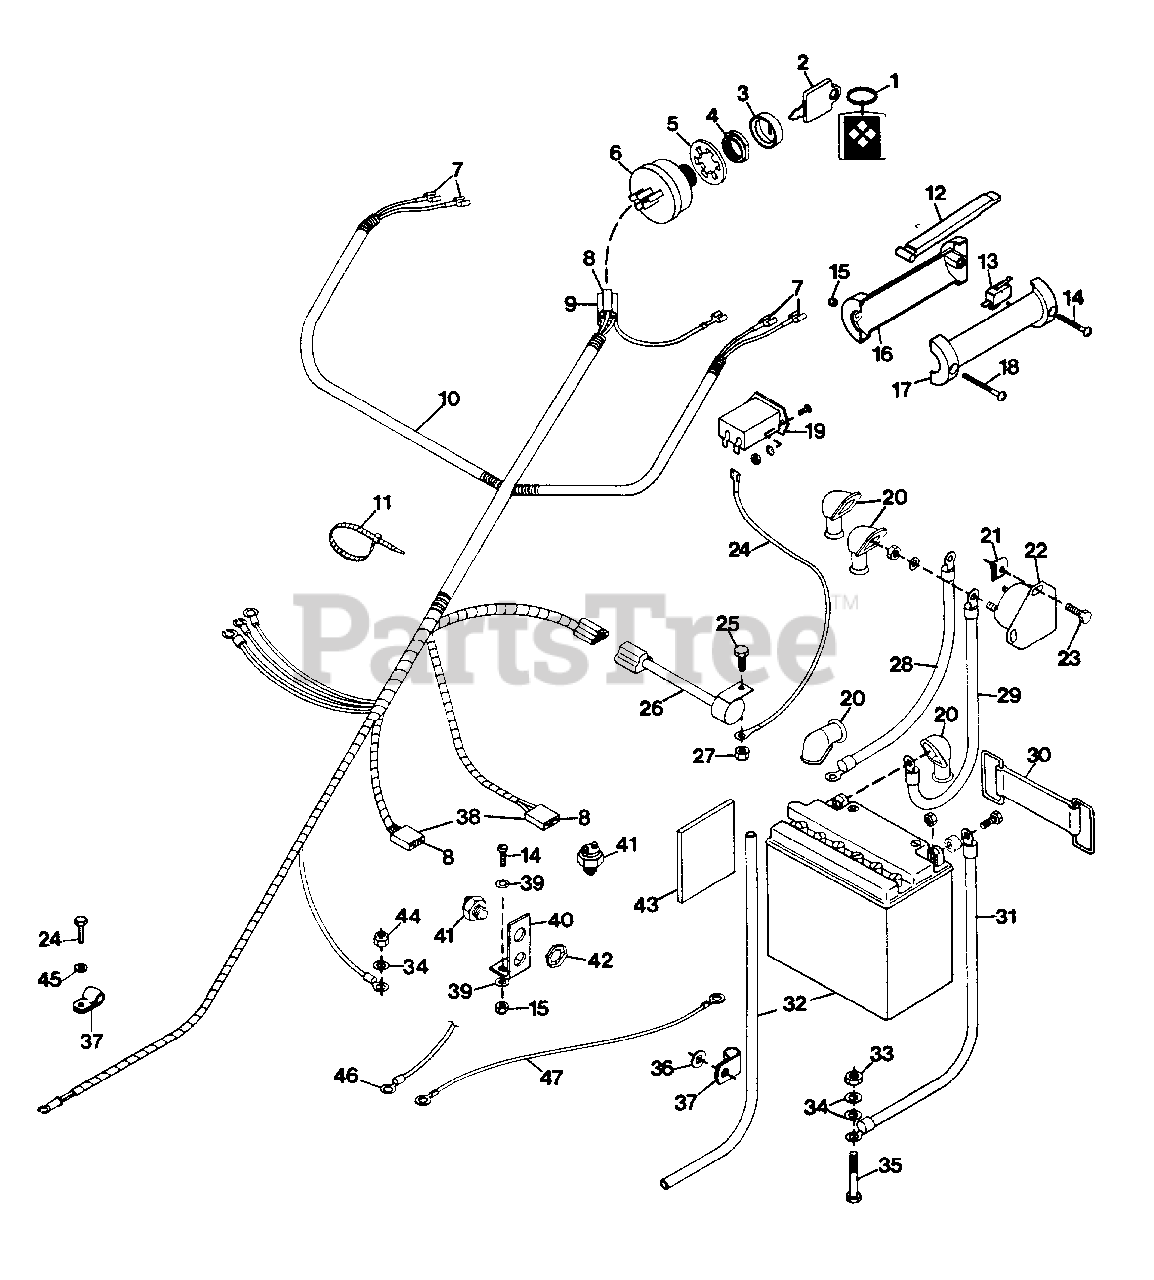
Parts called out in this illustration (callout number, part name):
1	CHAIN, KEY
2	KEY, IGNITION SWITCH
3	BOOT, FOR 9/16 SWITCH
4	NUT, 9/16-24 FOR SWITCH
5	WASHER, LOCK
6	SWITCH, IGNITION
7	TERMINAL, FEMALE
8	TERMINAL
9	CONNECTOR
10	HARNESS, WIRING
11	TIE, CABLE
12	LEVER
13	SWITCH
14	SCREW, MACHINE 10-24X.75 PHD
15	NUT, LOCK 10-24
16	HANDLE, R.H.
17	HANDLE, L.H.
18	SCREW, MACH. 10-24X1.50 PHDCR
19	HOURMETER
20	BOOT, BATTERY CABLE
21	NUT, SPEED 1/4-20
22	SWITCH, MAGNETIC
23	BOLT, HEX 1/4-20X.750
24	WIRE, INSTRUMENT PANEL
25	BOLT, HEX 1/4-20X.625
26	MODULE, INTERLOCK ELECTRIC
27	NUT, LOCK 1/4-20
28	CABLE, SOLENOID TO STARTER
29	CABLE, BATTERY TO SOLENOID
30	STRAP, BATTERY
31	CABLE, NEGATIVE BATTERY
32	BATTERY, 12 VOLT
33	NUT, HEX 5/16-18
34	WASHER, FLAT .344X.688X.065
35	BOLT, HEX 5/16-18X2.00
36	WASHER, FLAT .375X1.125X.065
37	CLAMP
38	CONNECTOR, 2-WIRE SWITCH
39	WASHER, FLAT .188X.438X.049
40	BRACKET, INTERLOCK SWITCH
41	SWITCH, NEUTRAL START
42	NUT, STAMPED 9/16-18
43	PAD, BATTERY 3.5X4.0
44	NUT, LOCK 5/16-18
45	WASHER, FLAT .281X.625X.065
46	TERMINAL, RING TONGUE
47	WIRE, GROUND
